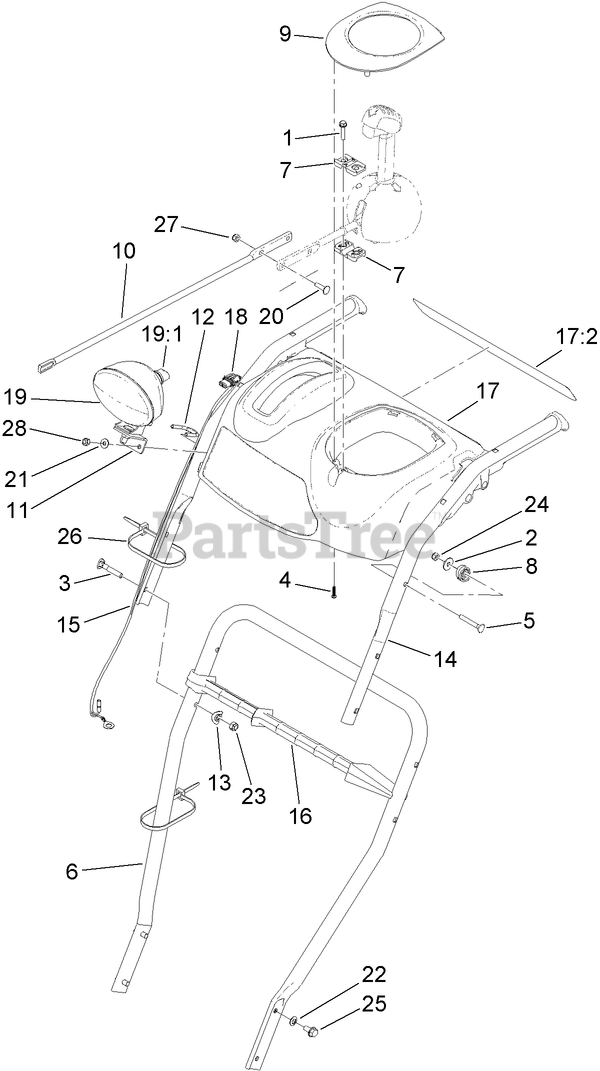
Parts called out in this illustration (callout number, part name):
1	SCREW-PLASTITE
2	WASHER-PLAIN
3	SCREW-HANDLE
4	SCREW-PPH
5	SCREW
6	HANDLE-LOWER
7	SUPPORT-ROD
8	CLAMP-CABLE
9	COVER-PANEL, CONTROL
10	ROD-CHUTE, FRONT
11	BRACKET-LIGHT
13	WASHER
15	HANDLE-UPPER, RH
16	STICK-CLEANOUT
17	PANEL-CONTROL
17:2	DECAL-WARNING
18	HARNESS-WIRE
19	HEADLAMP ASM
19:1	LAMP-12 VOLT
20	SCREW-CARR
21	WASHER-FLAT
22	WASHER-BELLEVILLE
23	NUT-LOCK, NI
24	NUT-LOCK, NI
25	SCREW-HWHTF
26	TIE-CABLE
27	NUT-LOCK, NI
28	NUT-LOCK, NI
